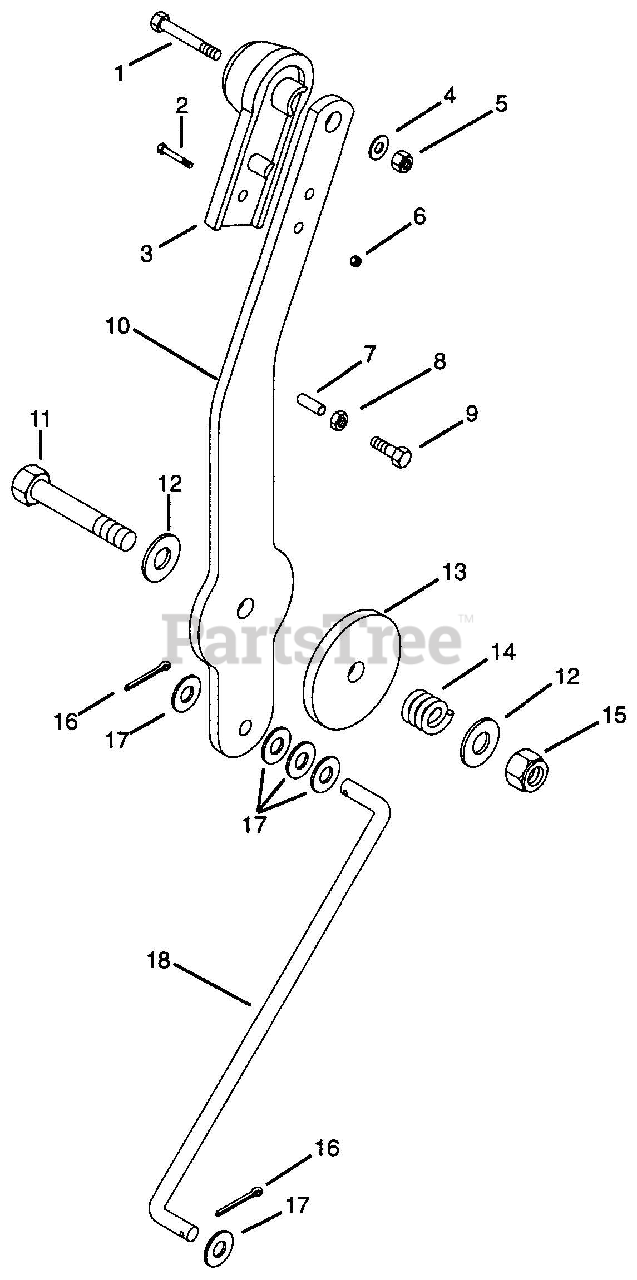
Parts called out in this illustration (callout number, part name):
1	Bolt-Hex .25-20 x 1.50 Grade 5
2	Screw-Machine 6-32 x .625
3	Know - Hand Control
4	Washer-Flat-Steel .281 x 625 x .065
5	Nut-Locking-Center .250-20 Grade 2
6	Nut-Locking-Machine 6-32 w/Insert
7	Cap
8	Nut-Hex .250-20 Grade 2
9	Bolt-Hex .25-20 x .75 Grade 5
10	Lever - Speed Control
11	Bolt-Hex .25-20 x .75 Grade 5
12	Washer-Flat-Steel .531 x 1.062 x .095
13	Disc - Friction Material
14	Spring - Compression .125 x .78 x 1.00
15	Nut-Locking-Center .50-13 Grade 5
16	Pin-Cotter .09 x 1.0
17	Washer-Flat-Steel .406 x .812 x .065
18	Rod - Speed Control
